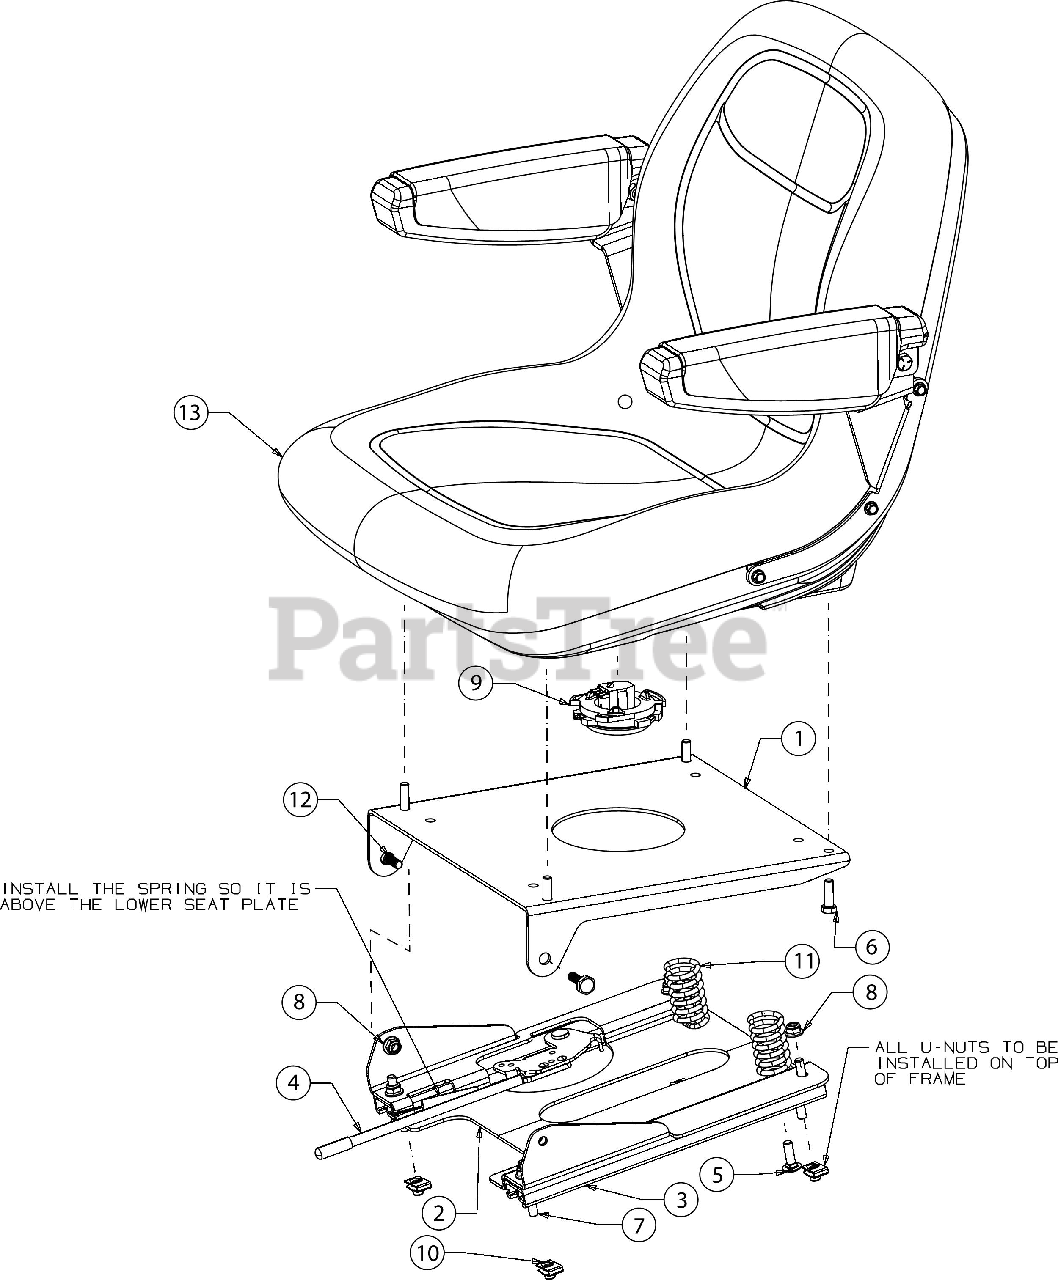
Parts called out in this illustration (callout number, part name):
1	SEAT MOUNTING BASE
2	SEAT MOUNTING PLATE
3	SEAT TRACK (W/O LATCH)
4	SEAT TRACK (W/LATCH)
5	CARRIAGE BOLT 5/16-18 x 1.00
6	SCREW 5/16-18 x 1.0 GR5
7	SCREW 5/16-18 x .625
8	FLANGE LOCK NUT 5/16-18
9	SEAT SWITCH NC/NC
10	U-NUT
11	COMPRESSION SPRING
12	SHOULDER SCREW .437
13	SEAT W/ARMREST
